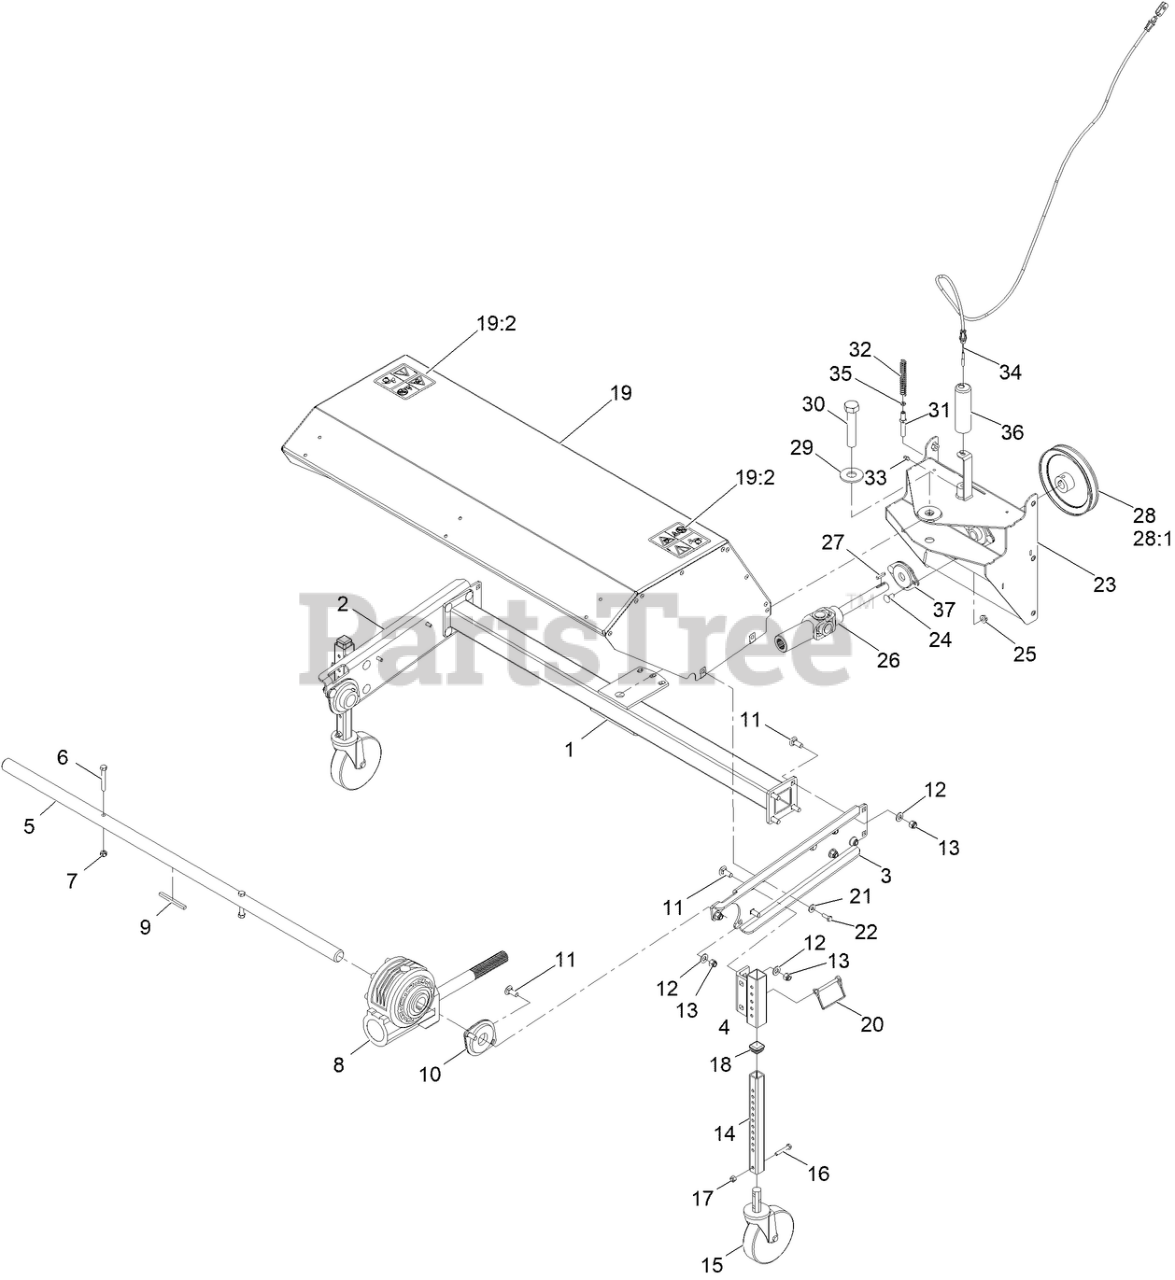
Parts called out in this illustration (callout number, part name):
2	ARM-RIGHT
3	ARM-LEFT
4	CASTER-BRACKET
6	SCREW-HH
7	NUT-HEX
8	GEARBOX-WORM
9	KEY-STRAIGHT
10	BEARING-FLANGE
11	SCREW-CARR
12	WASHER-FLAT
13	NUT-HEX
14	TUBE-SQUARE, HEIGHT ADJUS
15	CASTER-WHEEL
16	SCREW-HH
17	NUT-HEX
19	HOOD ASM, BLACK W/ DECALS
19:2	Decal-Warning Fly Obj-Entangle
20	PIN-WIRE, LOCK
21	WASHER-FLAT
22	SCREW-HH
23	FRAME-MOUNTING [BLACK]
24	BOLT-CARR
26	SHAFT-DRIVE
27	KEY-ROUND END
28	PULLEY-IMPELLER
28:1	SETSCREW
29	WASHER-FLAT
30	SCREW-HH
31	PIN-SWING
32	SPRING-COMPRESSION
33	FITTING-GREASE
34	CABLE-ANGLE, BROOM
35	NUT-HEX
37	BEARING-SHAFT
